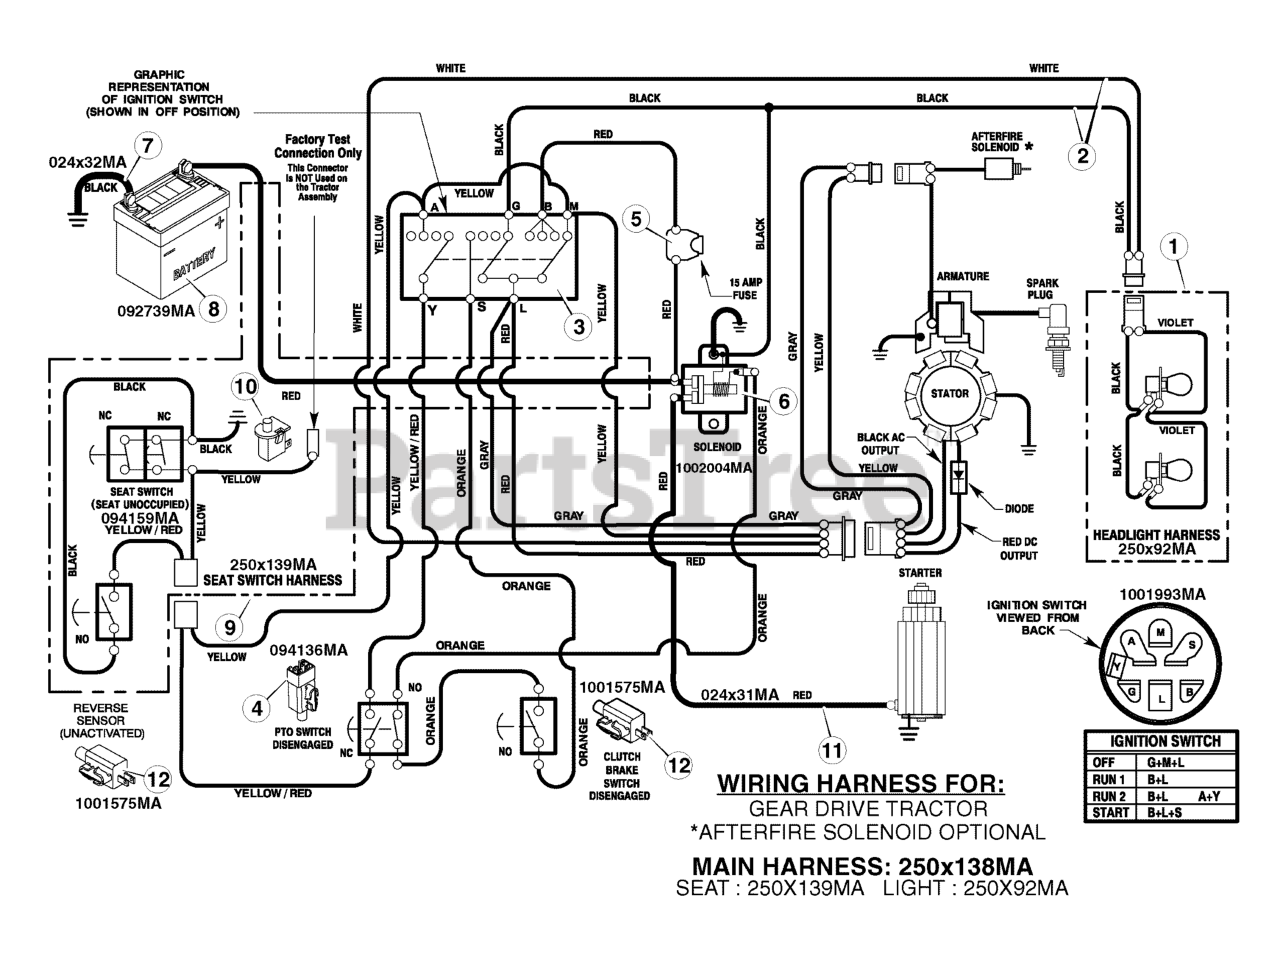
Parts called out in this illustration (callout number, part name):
1	Harness, Light Wire
2	Harness, Chassis Wire
3	Switch, Ignition
4	Switch, PTO
6	Solenoid
7	Cable, Battery Ground
8	Battery
9	Harness, Seat Switch Wire
10	Switch, Seat Sensor
12	Switch, Limit
